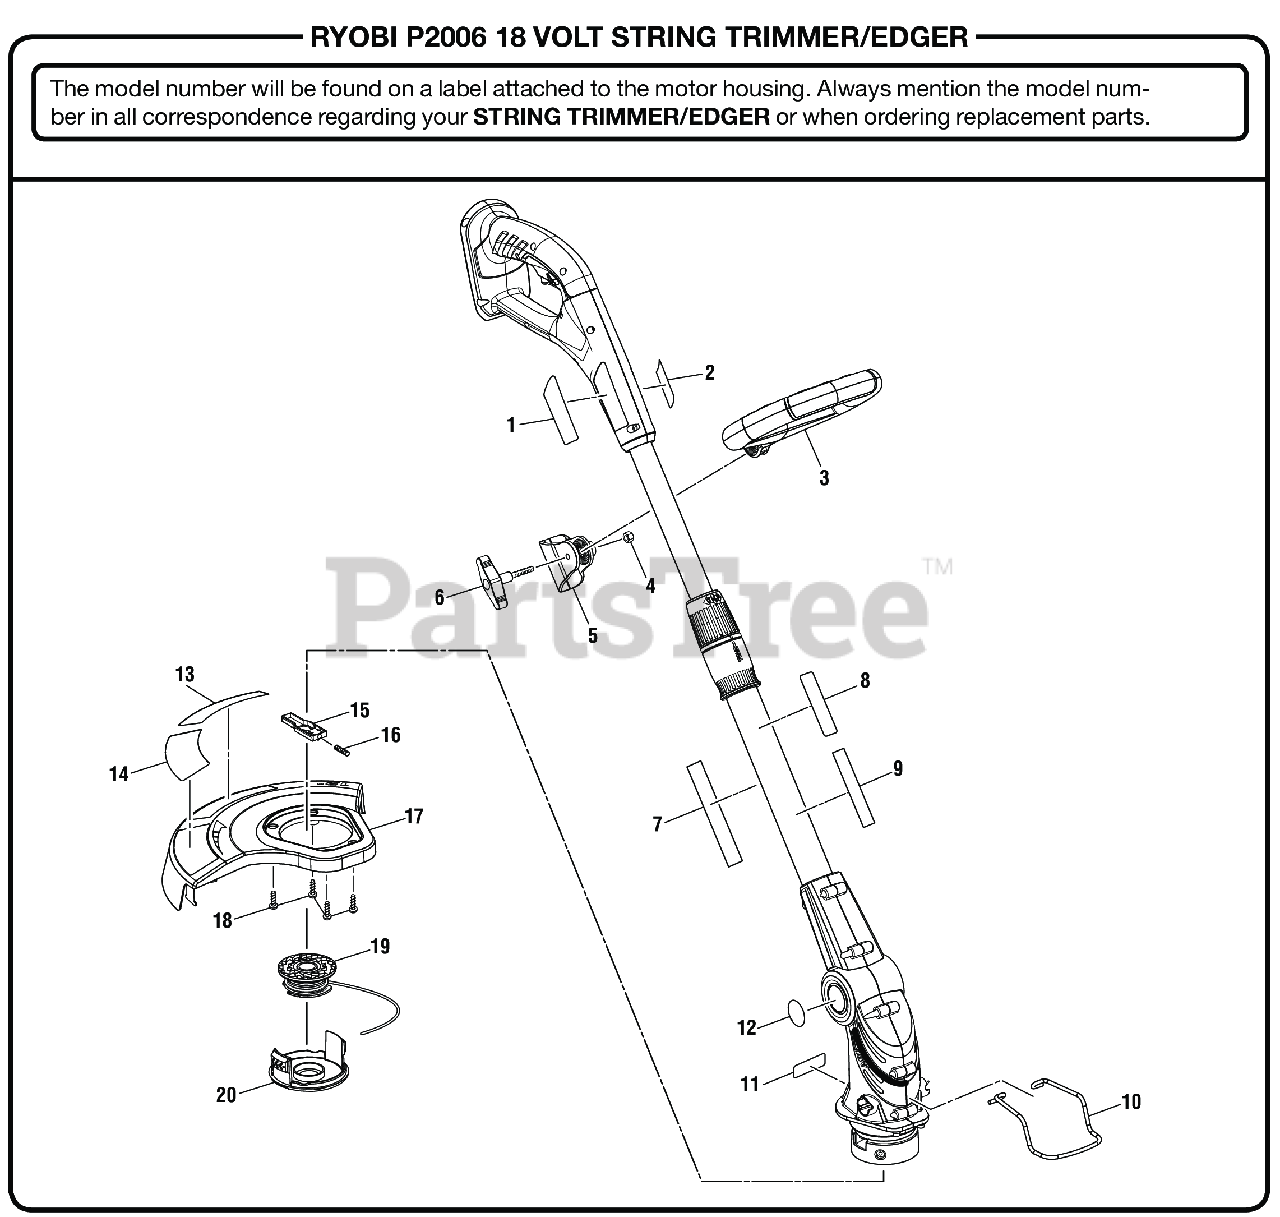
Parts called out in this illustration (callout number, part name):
1	Data Label
2	Logo Label (Handle)
3	Lower Auxiliary Handle
4	Lock Nut (M6)
5	Clamp Assembly
6	Knob Assembly
7	Warning Label (Fr/Sp)
8	Warning Label (Icon)
9	18V Lithium-Ion Label
10	Edger Guide
11	Logo Label (Housing)
12	Pivoting Head Label
13	Autofeed String Head Label
14	Adjustable Cutting Width Label
15	Slider Assembly
16	Compression Spring (Internal Tooth)
17	Grass Deflector Assembly
18	Screw (M4 x 12 mm, Pan Hd.)
19	Spool Assembly (.065 round-RY40021)
20	Spool Cap (AC14HCA)
